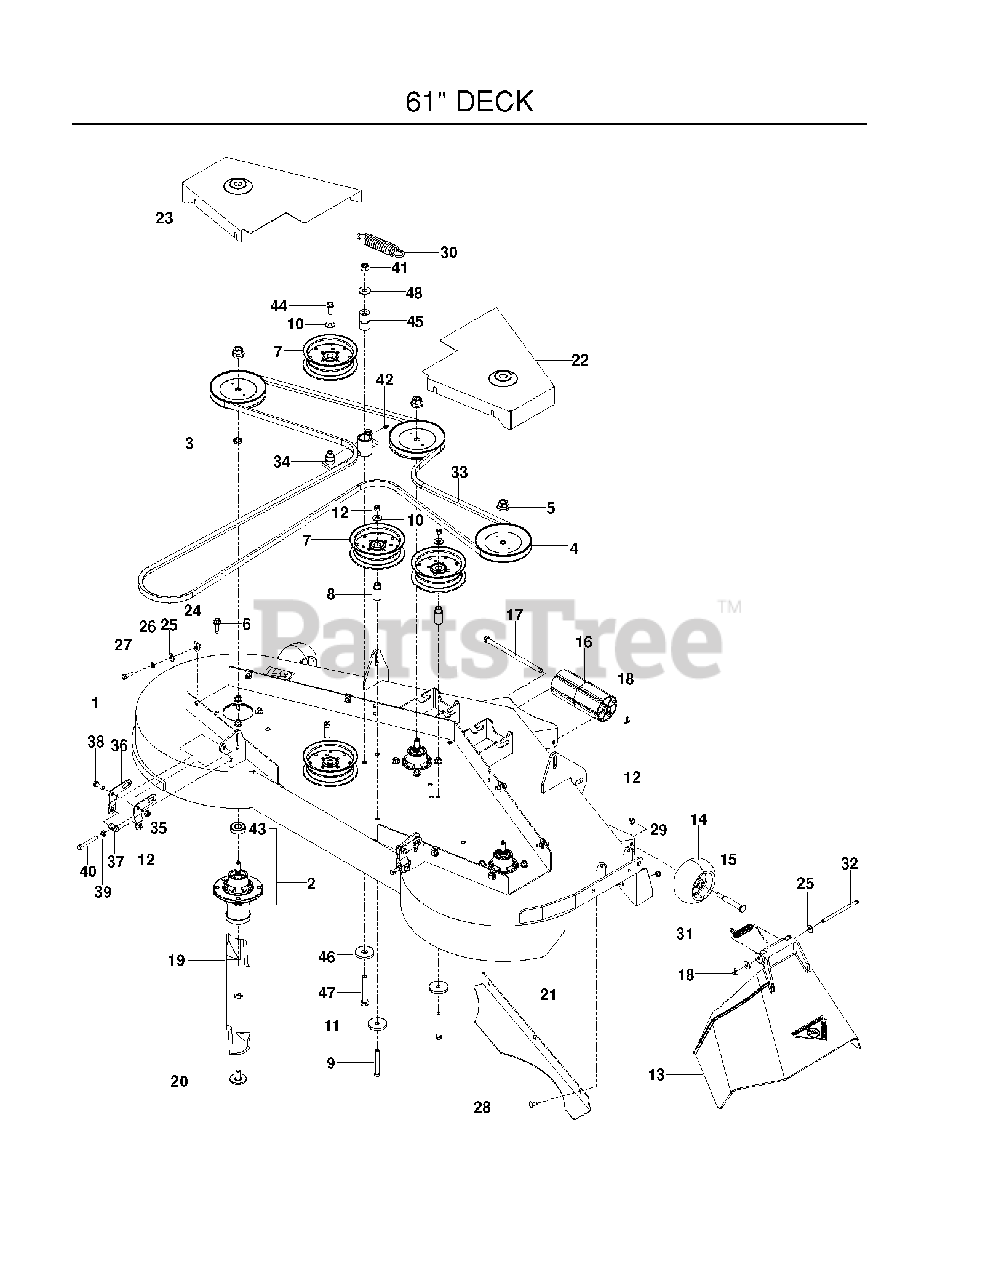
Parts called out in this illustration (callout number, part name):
1	DECK W/DECALS 61 RAM ULTRA
2	HOUSING ASM
5	LOCKNUT - 9/16
7	PULLEY, IDLER
8	IDLER BUSHING
9	HCS 3/8C X 3
10	WASHER 3/8 FLAT
11	SPINDLE WASHER
12	NUT 3/8-16 NYLOC
13	DISCHARGE CHUTE 61"
15	SHOULDER BOLT 1/2X2-5/8 ZD SPE
16	NOSEROLLER 48"
17	NOSE ROLLER ROD
18	COTTER PIN 1/8 X 3/4
19	BLADE, 21"
20	BOLT.WASHER.ASM.7/16-2
21	CONFINEMENT PLATE 61
22	SHIELD, BELT 61 BLUE RH
23	SHIELD, BELT 61 BLUE LH
24	U-CLIP 5/16-18 NUT RETAINER
25	WASHER 5/16 FLAT
26	WASH 5/16 DISC SPRING ZD
27	HCS 5/16C X 3/4
28	CARRIAGE BOLT 5/16C X 5/8"
29	NUT 5/16 NYLOC
31	SPRING - TORSION
32	PIN-CLEVIS 5/16 DIA X 5.19 ZD
34	IDLER ARM
35	PITCH, ADJUST, RT
36	PITCH, ADJUST, LT
37	TRUNION, PITCH
38	HCS 3/8C X 1
39	NUT 5/16C HEX
40	HCS 5/16-18 X 2 1/2 TPBLT
41	NUT 1/2-13 HEX NYLOC ZD
42	ZERK
43	BEARING, BALL
44	HCS 3/8C X 1 SERRATED HEAD
45	PIVOT BUSHING
46	WASHER, SUPPORT
47	HCS 1/2C X 3 1/4
48	WASHER 1/2 FLAT
